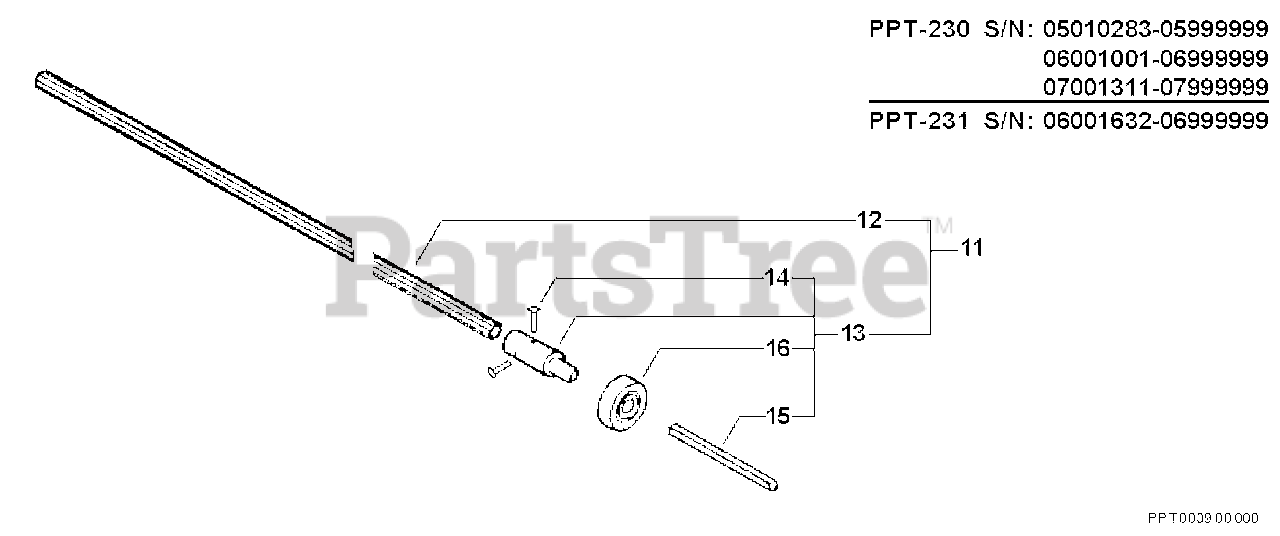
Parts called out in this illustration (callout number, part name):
11	SHAFT ASSY, DRIVE
12	DRIVESHAFT
13	CONNECTOR, DRIVE SHAFT
16	BEARING, BALL 6002 DDU
